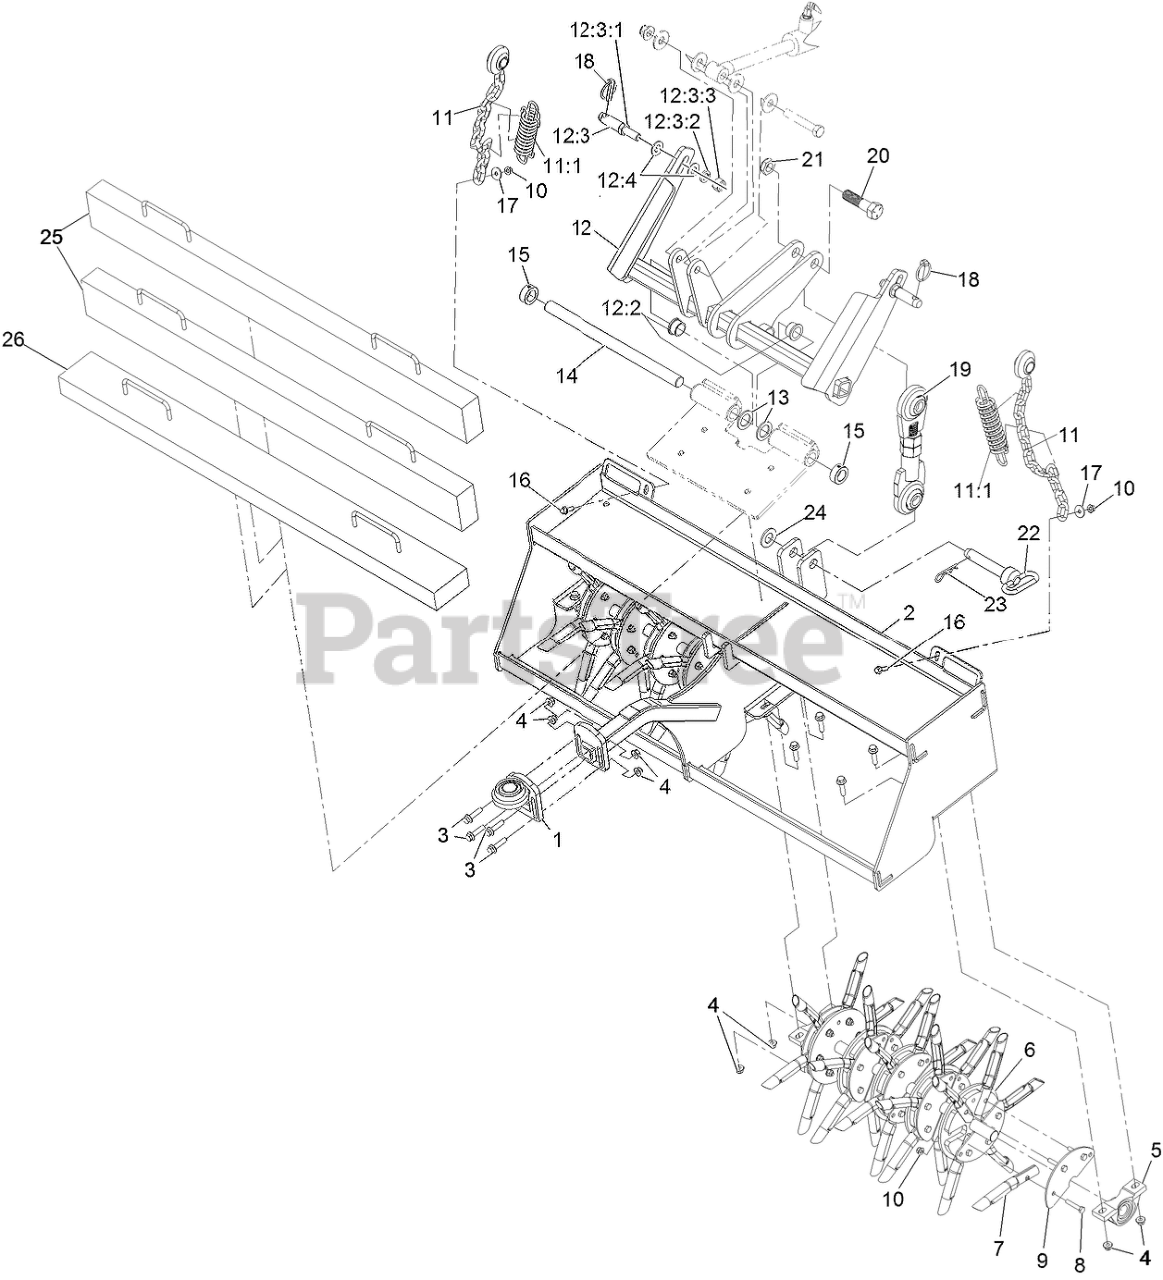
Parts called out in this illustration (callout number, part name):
1	MOUNT-SWIVEL BRG,AER HEAD
2	HEAD-AERATION, 40""
3	SCREW-HHF
4	NUT-HF, NI
5	PILLOW BLOCK BEARING
6	REEL-TINE
7	TINE-CORING (3/4 INCH)
8	SCREW-HH
9	DISK, HALF, AE
10	NUT-HF, NI
11	SWIVEL-CHAIN ASM
11:1	Z-PLUG DRAWBAR SPRING
12	ARM-LIFT, ASM
12:2	BUSHING-FLANGE
12:3	7/8 X 4-1/2 LIFT PIN\N21
12:3:1	NUT-JAM
12:3:2	WASHER-LOCK
12:3:3	NUT-HEX
12:4	WASHER-FLAT
13	WASHER-THRUST
14	PIVOT-LIFT ARM
16	SCREW-HH
17	WASHER-FLAT
18	PIN-LYNCH
19	BALL SWIVEL, ADUSTABLE LI
20	7/8-9 X 3-1/4 GR8 HEX CAP
21	NUT-LOCK, NI
22	7/8 X 4 HITCH PIN RED HAN
23	PIN-HAIR
24	WASHER-FLAT
25	112LBS WEIGHT\N45.25
26	WEIGHT-HORIZ, ZPLUG
